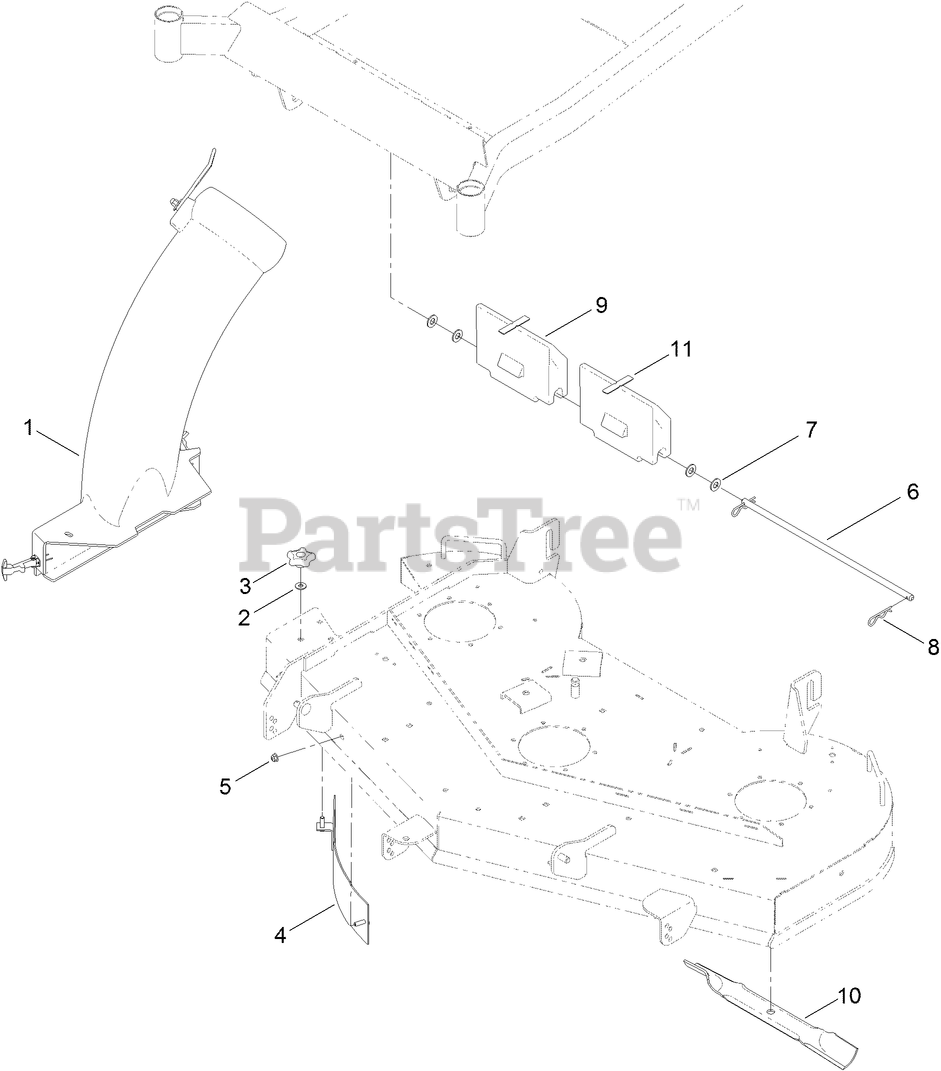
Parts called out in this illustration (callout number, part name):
1	CHUTE ASM
2	WASHER-FLAT
4	BAFFLE-BAGGER
5	NUT-HF, NI
6	ROD-DECK, PIVOT
7	WASHER-FLAT
8	PIN-HAIR
9	WEIGHT-BAGGER
10	BLADE-HI LIFT
11	BUMPER-PAD
